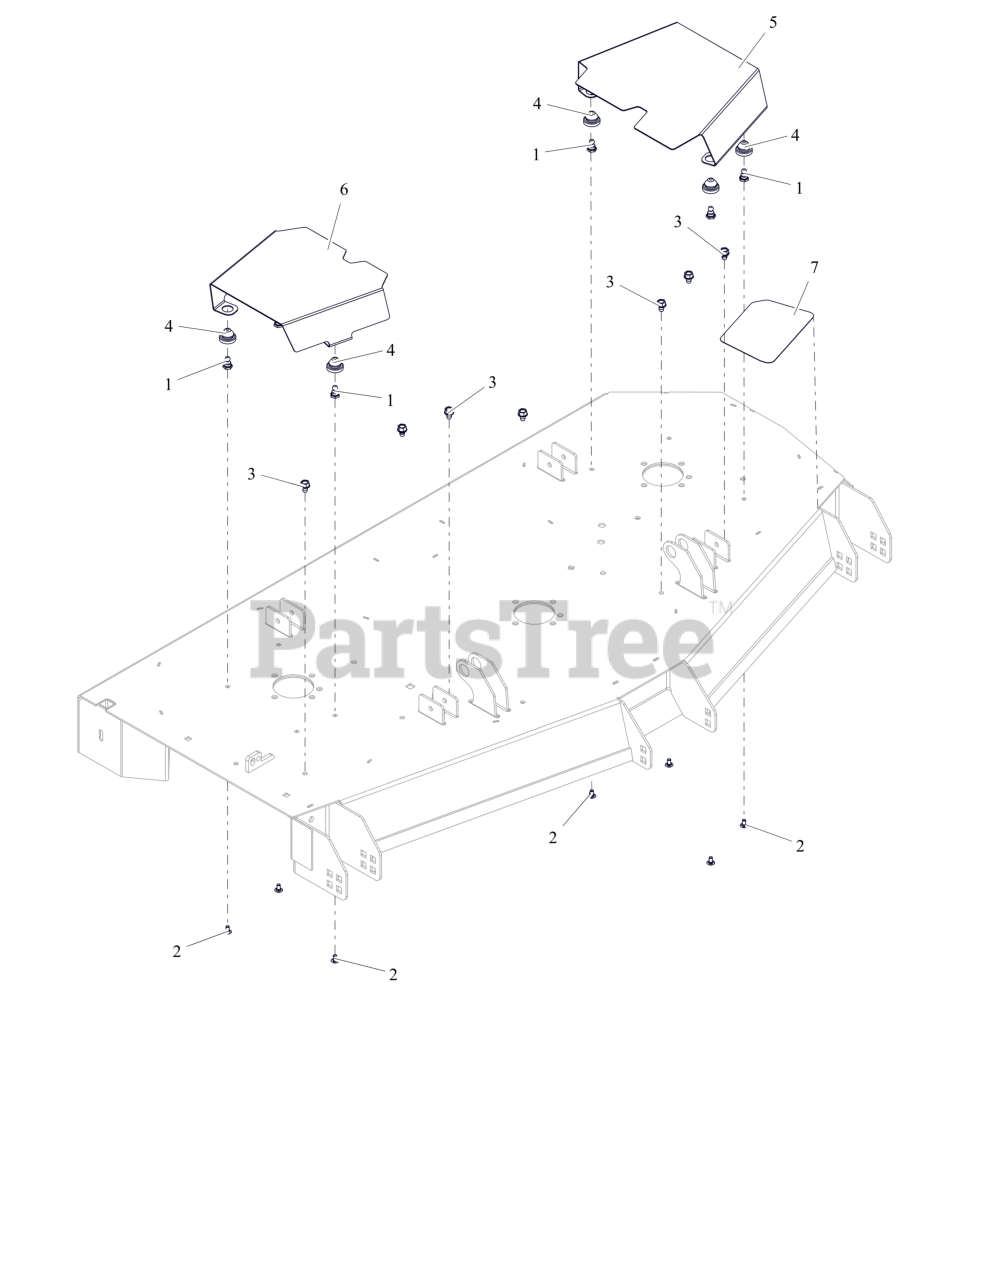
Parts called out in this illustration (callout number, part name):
1	STUD, BALL FEMALE .250-20 THREAD
2	BLT, RHSSN.25-20X.500 G5 ZCC
3	SCR,TAP .375-16X.50 HWH TR ZCC
4	COUPLING, RUBBER PUSH-IN
5	COVER- BELT 60" LEFT
6	COVER- BELT 60" RIGHT
7	GRIP, STEP ANTI SKID HD XF3
